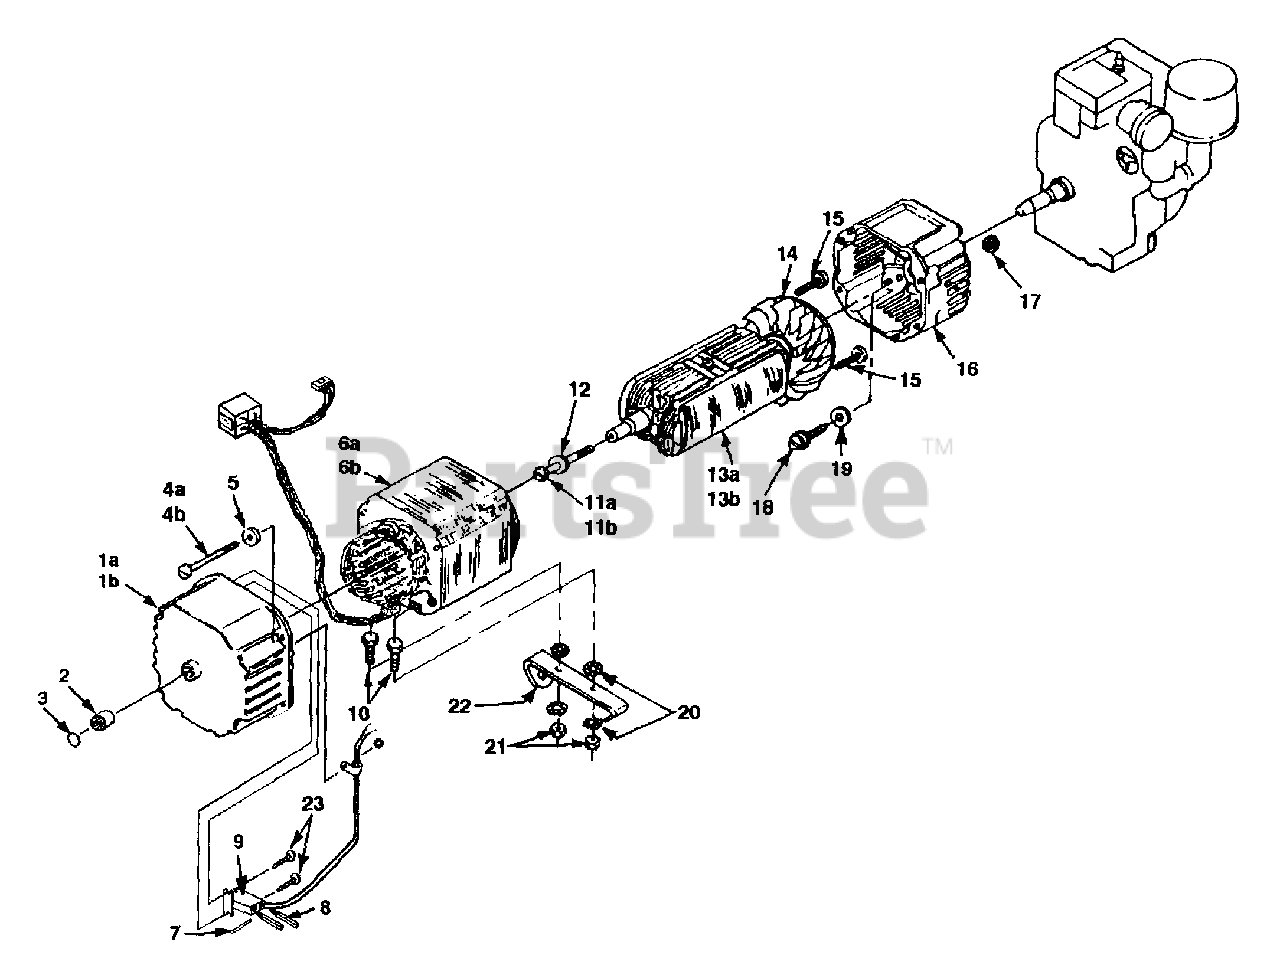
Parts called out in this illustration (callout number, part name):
1A	COMP. BRUSH HEAD(LRI4400 & LRIE4400, LRI5500, LRIE5500)
1B	COMP. BRUSH HEAD(LRI4400/CSA, LRIE4400/CSA, LRI5500/CSA, LRIE5500/CSA)
2	BEARING-Needle
3	EXPANDER-Plug
4A	BOLT-Stator (LRI & LRIE 4400'S)
4B	BOLT-Stator (LRI & LRIE 5500'S)
5	WASHER-Flat
6A	STATOR & HARNESS (LRI & LRIE4400'S)
6B	STATOR & HARNESS (LRI & LRIE5500'S)
8	BRUSH
9	BRUSH HOLDER
10	SCREW-Hex Hd. (5/16-18 X 3/4")
11A	BOLT-Rotor (LRI & LRIE 4400'S)
11B	BOLT-Rotor (LRI & LRIE 5500"S)
12	WASHER-Lock (5/16")
13A	ROTOR (LRI & LRIE 4400'S)
13B	ROTOR (LRI & LRIE 5500'S)
14	FAN-Generator
15	SCREW-Pan Hd. (6-19 X 3/4")
16	END BELL
17	NUT-Hex (1/4-20)
18	SCREW-Hex Hd. (3/8-16 X 3/4")
19	WASHER-Lock
20	WASHER-Lock (int./ext.)
21	NUT-Hex (5/16-18)
22	GENERATOR SUPPORT
23	SCREW-Pan Hd. (6-19 X 3/4")
